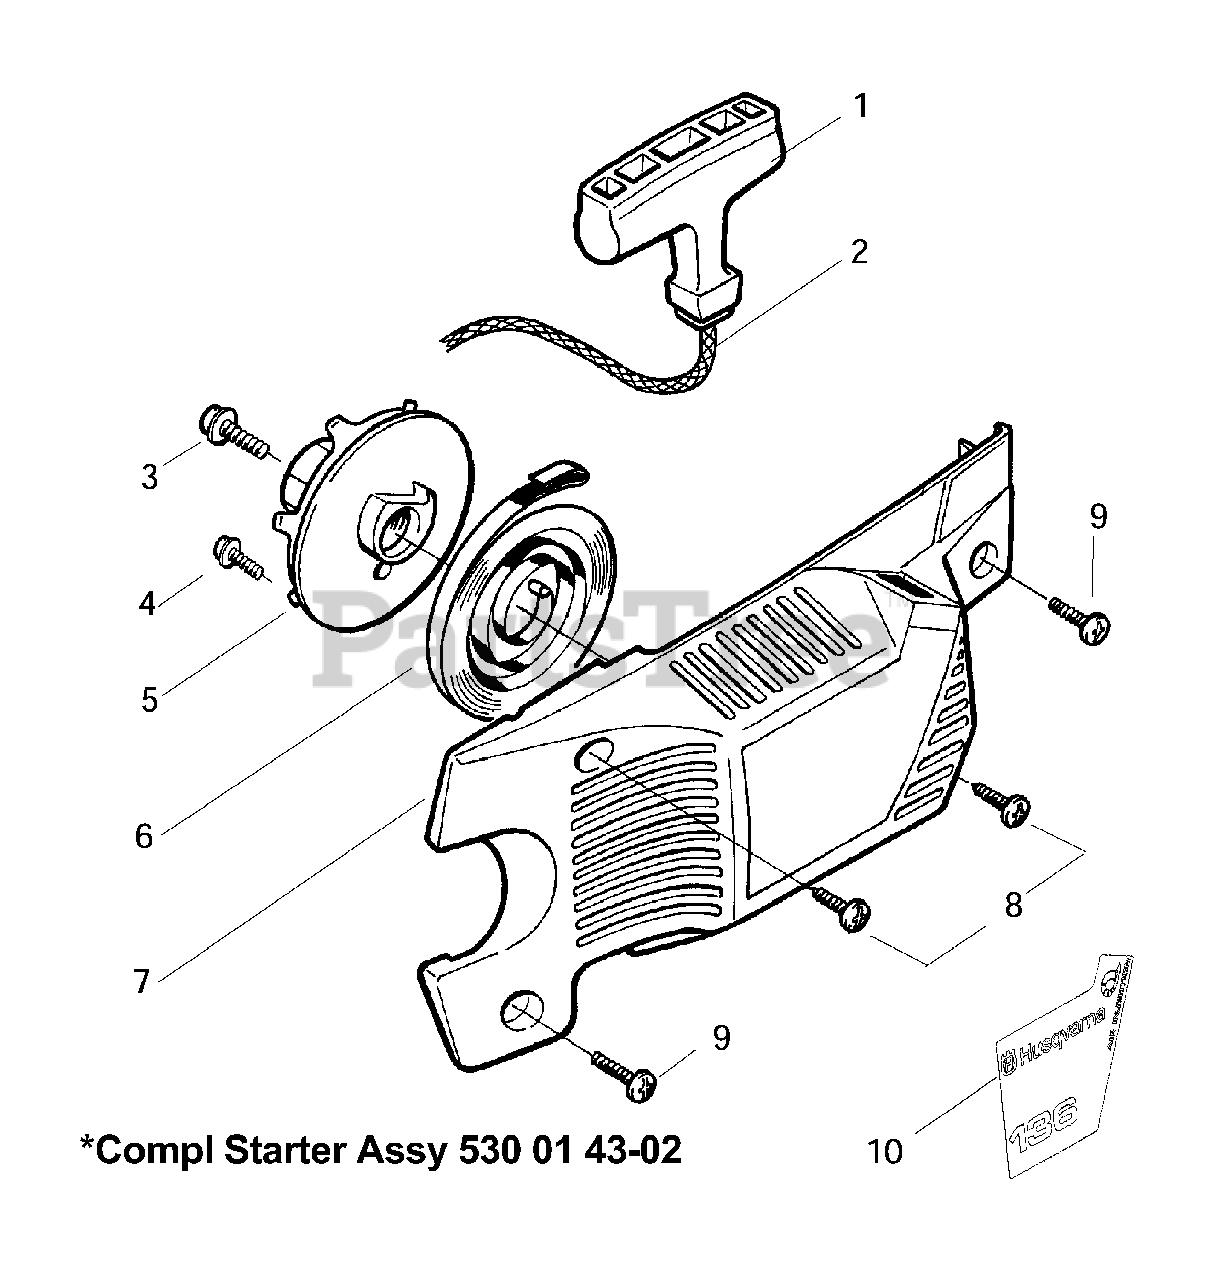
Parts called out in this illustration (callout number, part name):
1	Starter Handle
5	Starter-Pulley Kit
6	Recoil Spring
7	Fan Housing Assembly
10	Decal-Model 136
10	Decal-Model 141
530014302	Starter Assy.
